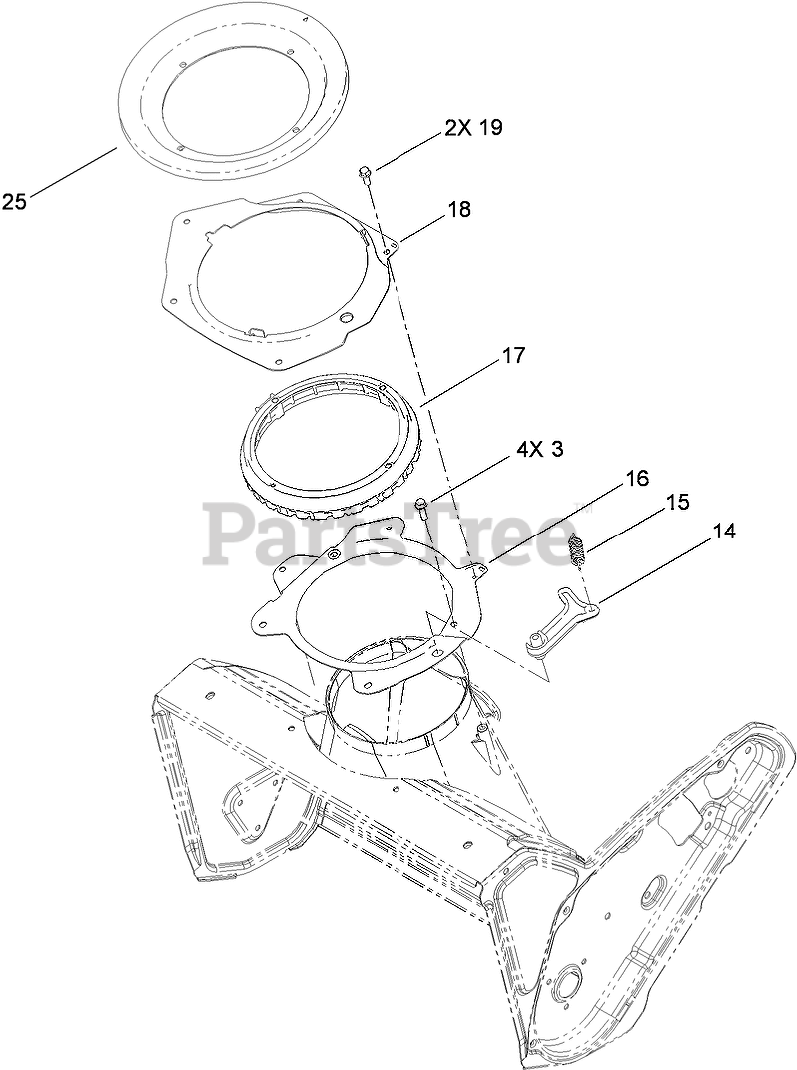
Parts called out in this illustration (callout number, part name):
3	SCREW-HWH
14	PAWL-DETENT
15	SPRING-EXTENSION
16	RING-SUPPORT, CHUTE
17	RING-CHUTE, DETENT
18	RETAINER-RING, CHUTE
19	SCREW-HWH
25	SEAL-RING, CHUTE
